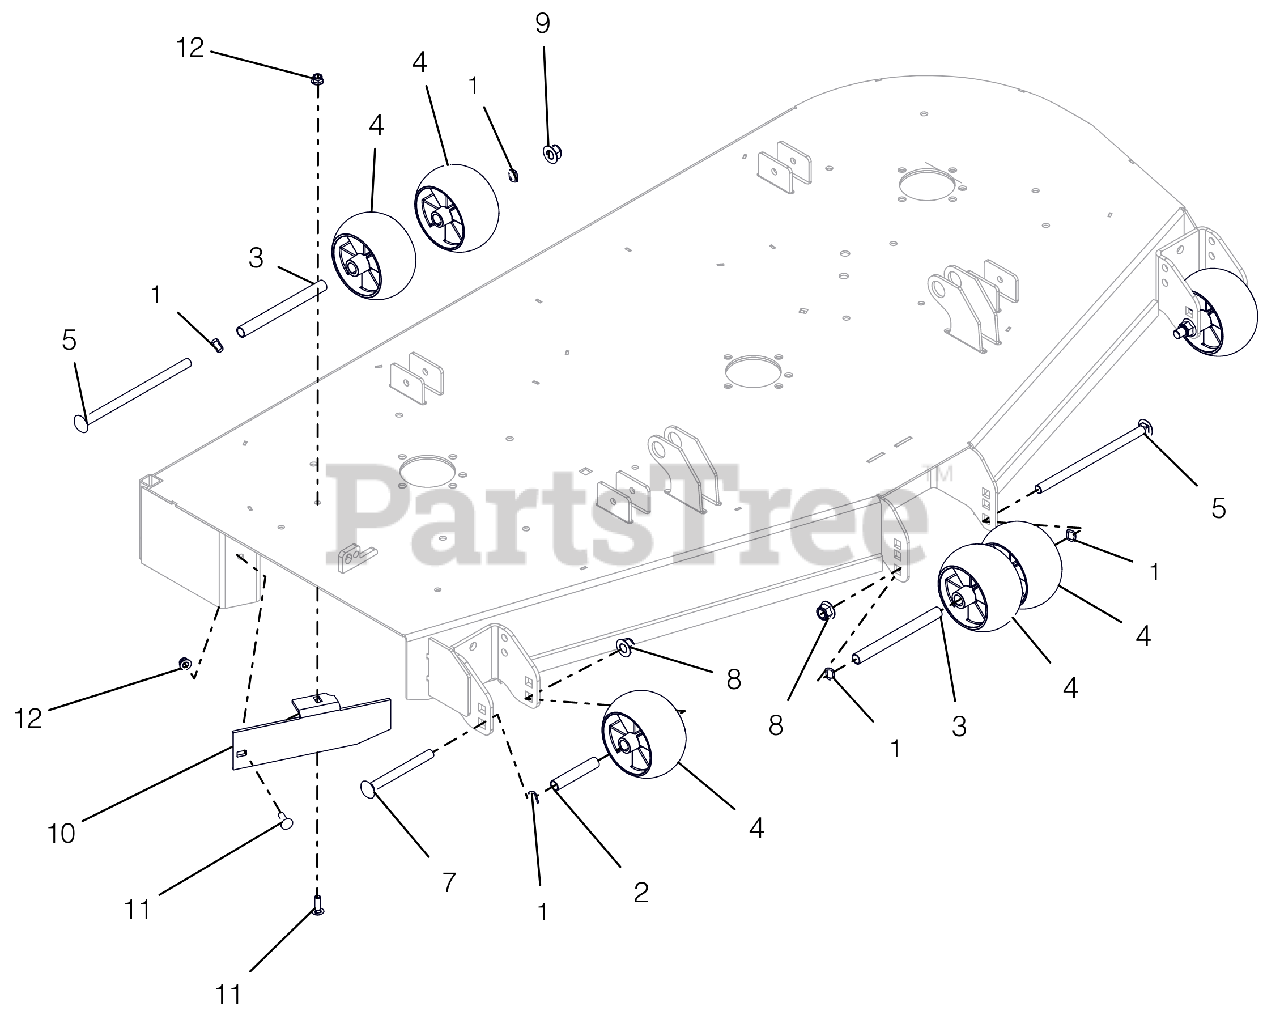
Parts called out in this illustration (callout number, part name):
1	WAVE WASHER .531X.781X.125FH
2	SPACER, .510X.625X3.35
3	SPACER, .510X.625X6.50
4	ANTI-SCALP WHEEL - 5X3 CTR
5	@BLT-RDHDSQNK .50-13X8.50 G5YZ
7	BLT-RDHDSQNK .50-13X5.00 GR5YZ
8	@NUT-LK-NYL-FLG .50-13 YWZC
9	@NUT-LK-NYL-FLG .50-13 YWZC
10	BAFFLE, 60" DISCHARGE
11	@BLT-RDHDSQNK .31-18X1.00 G5YZ
12	@NUT-LK-NYL-FLG .31-18 YWZC
